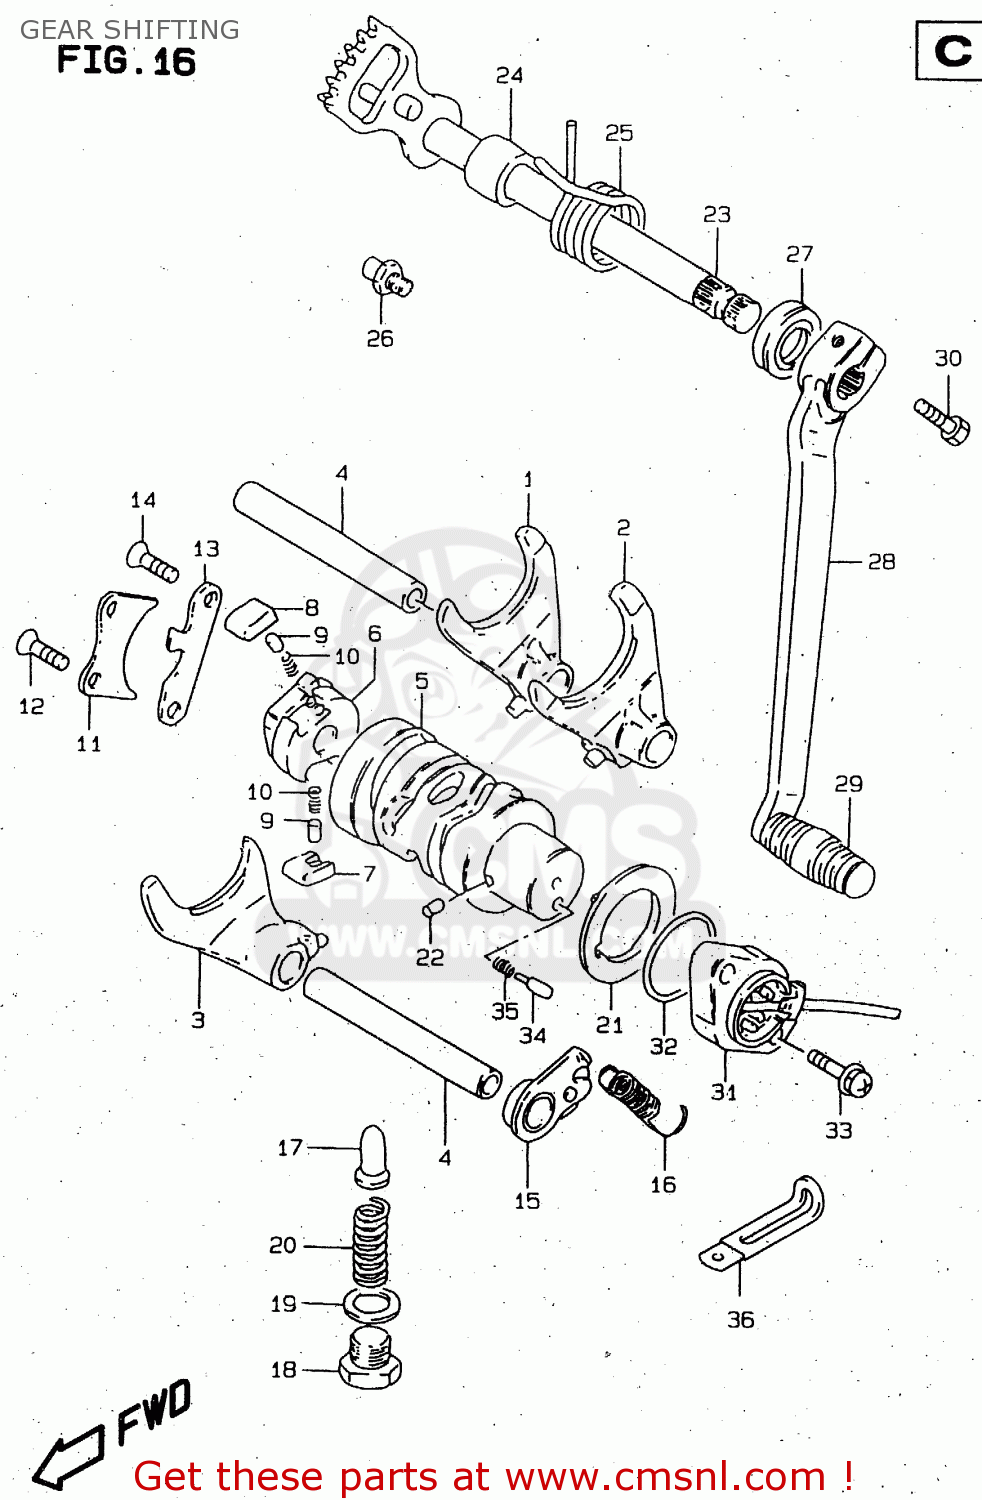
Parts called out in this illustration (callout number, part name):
1	FORK,GEAR SHIFT NO.1
2	FORK,GEAR SHIFT NO.1
3	FORK,GEAR SHIFT NO.3
4	SHAFT,GEAR SHIFT FORK
5	CAM,GEAR SHIFT
6	GEAR,GEAR SHIFT CAM DRIVEN
7	PAWL,GEAR SHIFT NO.1
8	PAWL,GEAR SHIFT NO.2
9	PIN(5X8)
10	SPRING
11	LIFTER,GEAR SHIFT POLE
12	SCREW
13	GUIDE,GEAR SHIFT CAM
14	SCREW
15	STOPPER,GEAR SHIFT CAM
16	SPRING
17	STOPPER,GEAR SHIFT CAM NO.2
18	PLUG(14X12)
19	GASKET(13.8X18.8X4.8) (NAS)
20	SPRING
21	PLATE,GEAR SHIFT CAM STOPPER
22	PIN
23	SHAFT,GEAR SHIFT
24	SPACER(12X20X15.3)
25	SPRING
26	STOPPER,GEAR SHIFT CAM
27	OIL SEAL
28	LEVER ASSY,GEAR SHIFT
29	RUBBER,GEAR SHIFT PEDAL
30	BOLT
31	BASE ASSY,GEAR SHIFT TERMINAL
32	O-RING (D:2.4 ID:26.2)
33	SCREW
34	PIN(5X15.5)
35	SPRING
36	CLAMP(L:65)
